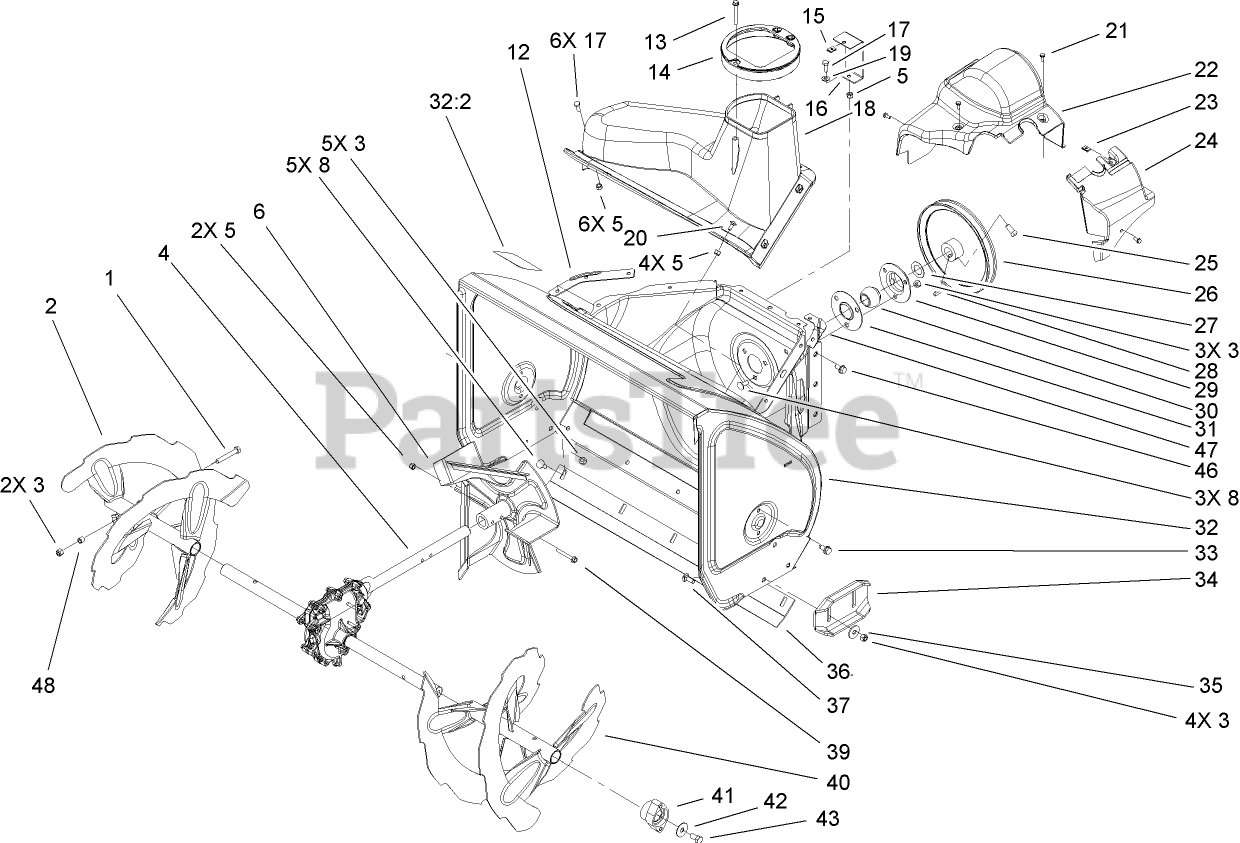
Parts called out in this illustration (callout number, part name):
1	SCREW-HH
2	RH AUGER ASM
3	NUT-LOCK, NI
5	NUT-LOCK, NI
6	IMPELLER ASM
8	SCREW-CARR
12	SEAL-FLANGE, COVER
13	SCREW-PLASTITE
14	GUIDE-CHUTE
15	NUT-SPEED
16	BRACKET-COVER, CLIP NUT
17	SCREW-HH
19	WASHER-FLAT
20	BOLT-CARR
21	SCREW-HWH
23	NUT-SPEED
24	COVER-EXTENSION, BELT
25	SCREW-SET, SQH
27	WASHER-THRUST
28	KEY-WOODRUFF
29	FLANGE-CUP, BEARING
30	BEARING-BALL
31	FLANGE-CUP, BEARING
32	HOUSING-AUGER, 28 INCH
33	SCREW-HWHTF
35	WASHER
36	SCRAPER-FIXED
37	SCREW-CARR
39	SCREW-HHF
40	LH AUGER ASM
41	BEARING-AUGER
42	WASHER
43	SCREW-HH
46	SCREW-HWHTF
48	SPACER
